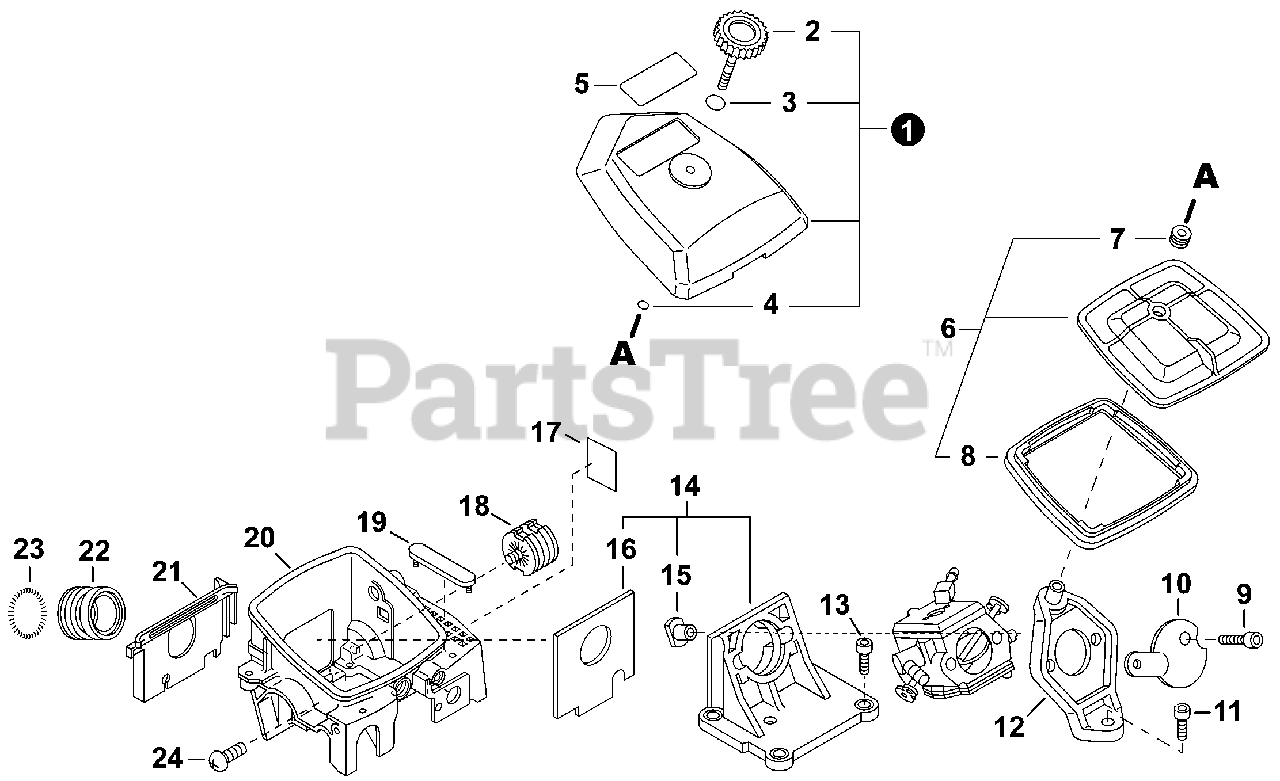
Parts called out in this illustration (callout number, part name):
1	COVER ASSY, AIR FILTER
2	THUMBSCREW
3	O-RING 10
4	O-RING 3
5	LABEL - MODEL - CS-8000
6	FILTER ASSY, AIR
8	SEAL, AIR FILTER
9	BOLT 5x55
11	BOLT 5x20
12	BRACKET, AIR FILTER
13	BOLT 5x25
14	INSULATOR KIT, INTAKE
16	SEAL, DUST
19	PLUG
20	CASE, CARBURETOR - GRAY
20	CASE, CARBURETOR - ORANGE
21	PLATE, GUIDE
22	ADAPTOR, INTAKE
24	SCREW 4x8
